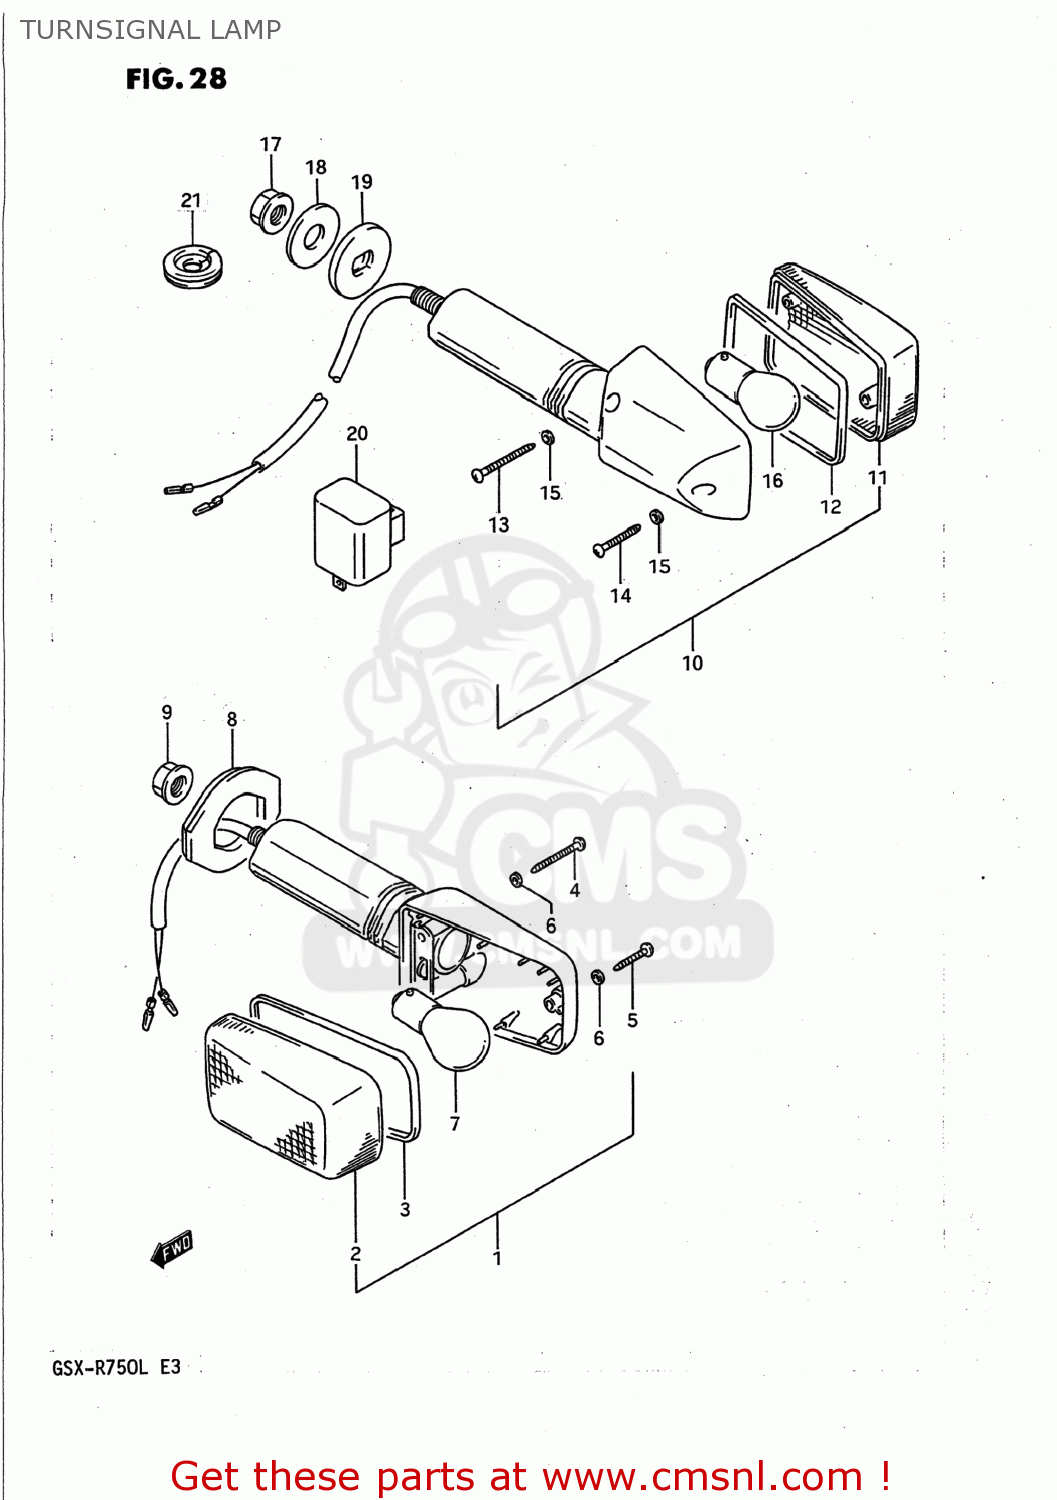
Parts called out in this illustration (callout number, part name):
1	LAMP ASSEMBLY,FRONT TURN SIGNAL
2	LENS
3	GASKET (NAS)
4	SCREW(3X30)
5	SCREW
6	GASKET (NAS)
7	BULB(12V21W)
8	GROMMET
9	NUT
10	LAMP ASSY,FR TURN SIGNAL
11	LENS
12	GASKET (NAS)
13	SCREW(3X30)
14	SCREW
15	GASKET (NAS)
16	BULB(12V21W)
17	NUT
18	WASHER(10.5X30X3.2)
19	SPACER,RR TURNSIGNAL
20	RELAY ASSEMBLY,TURN SIGNAL
21	GROMMET
